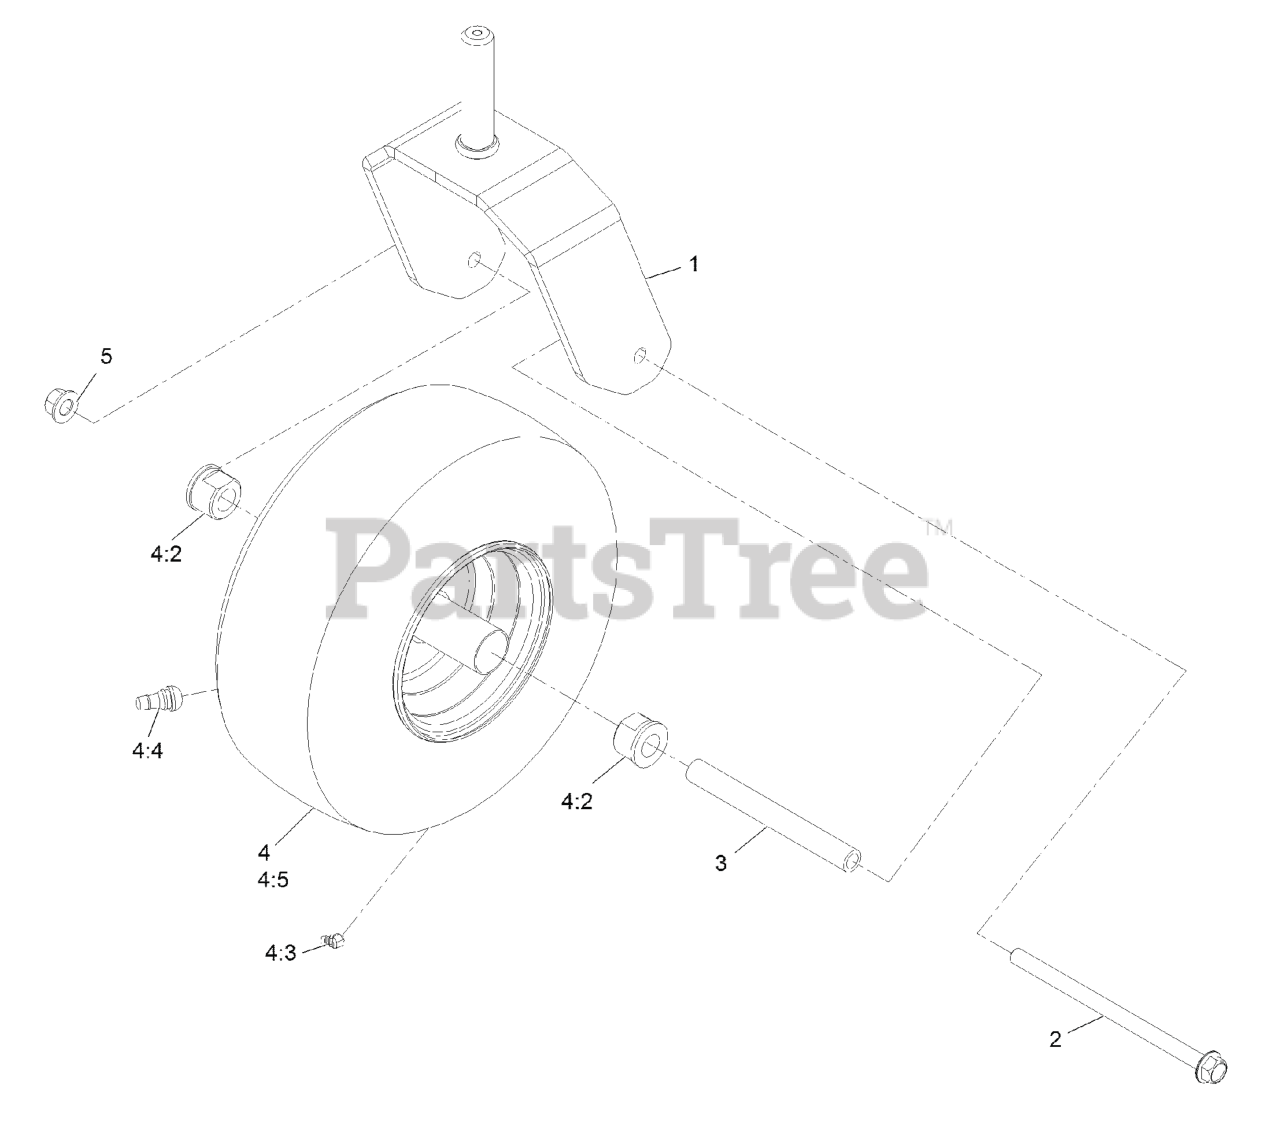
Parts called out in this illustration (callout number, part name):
1	FORK-CASTER
2	SCREW-HHF
3	SPANNER-WHEEL, CASTER
4	ASM, TIRE & WHEEL
4:2	BUSHING-FLANGE
4:3	FITTING-ZERK
4:4	VALVE
5	Nut-Lock 1/2-13
